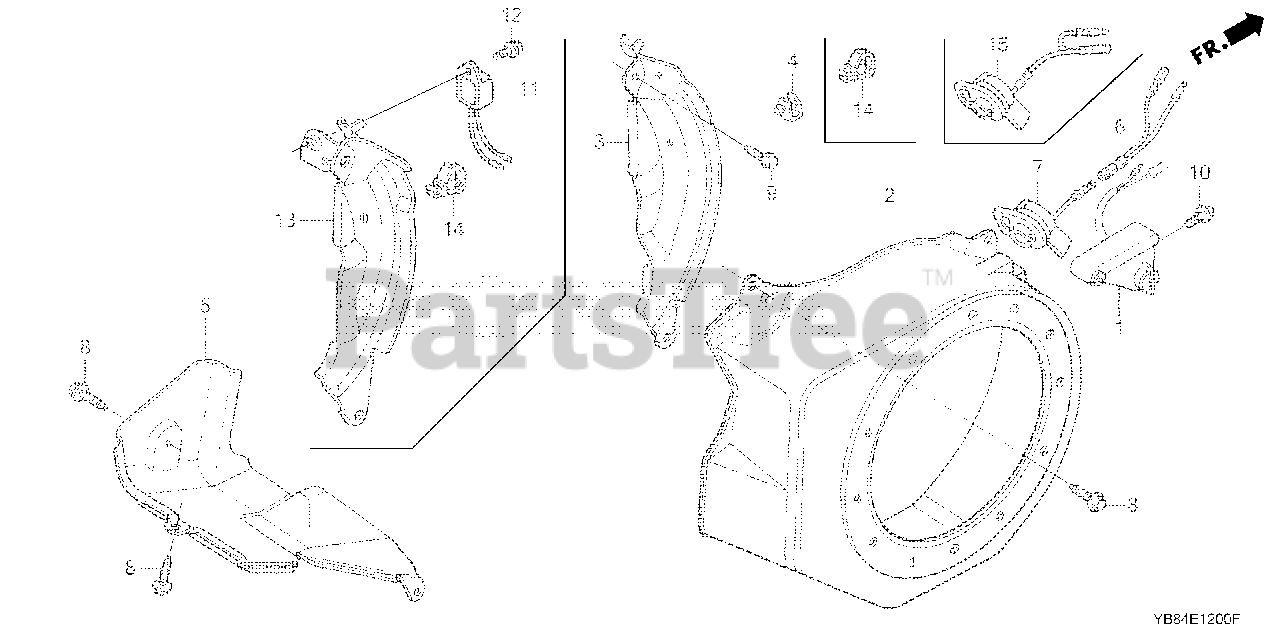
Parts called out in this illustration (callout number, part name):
2	COVER, FAN *R280* (POWER RED)
3	PLATE, SIDE (OIL ALERT)
4	CLAMP, CORD
6	SUB-HARNESS
7	SWITCH ASSY., ENGINE STOP
8	BOLT, FLANGE (6X12) (CT200)
9	BOLT, FLANGE (6X20) (CT200)
11	ALERT UNIT, OIL
12	BOLT, FLANGE (6X8)
13	PLATE, SIDE (OIL ALERT)
14	CLIP, HARNESS
